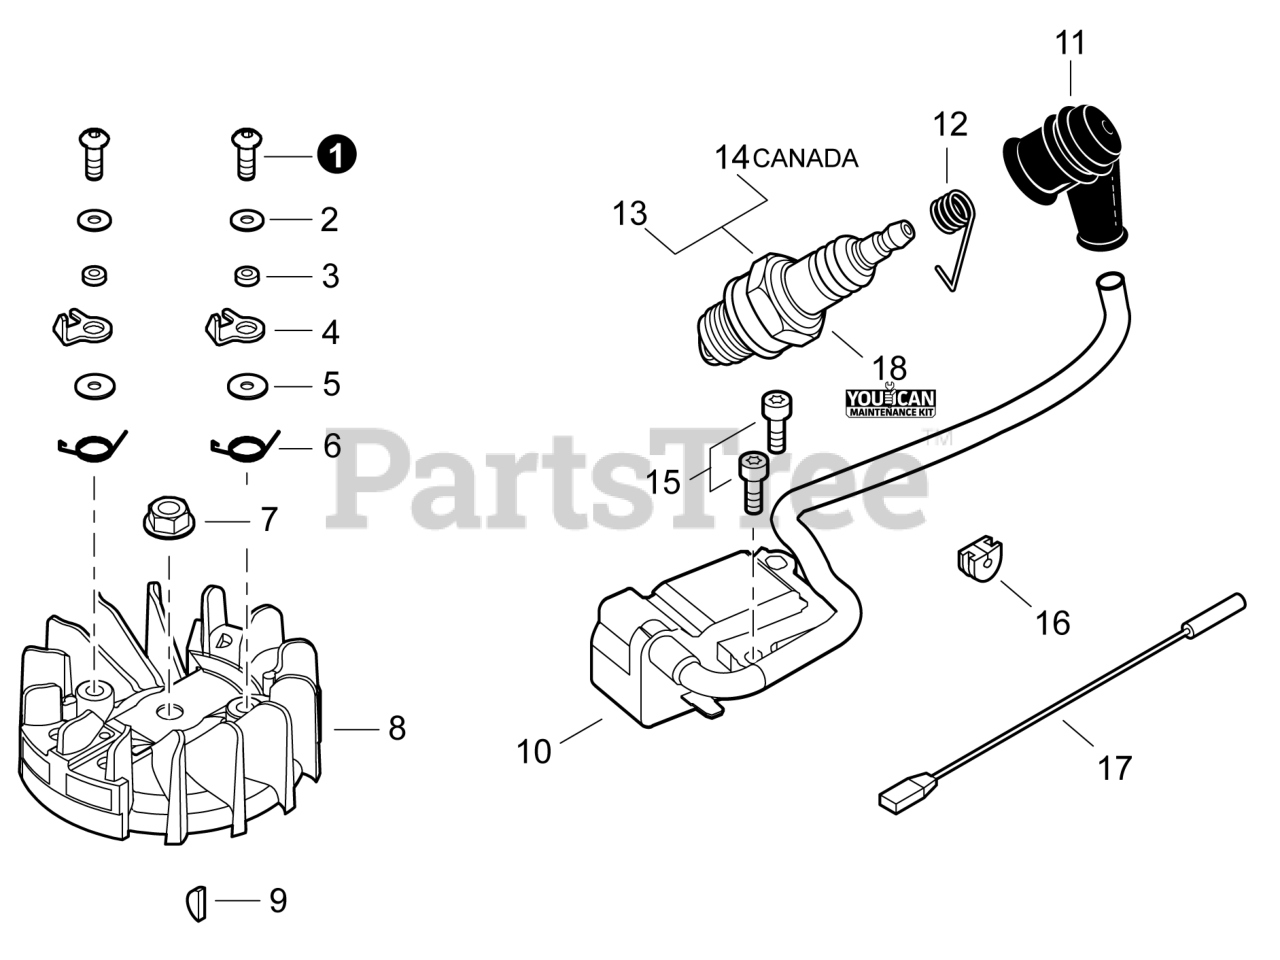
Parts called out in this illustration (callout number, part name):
1	BOLT 5x14
2	WASHER 5.5x12x0.8
5	WASHER 5.5x16x0.8
6	SPRING, TORSION
7	NUT, FLANGE M6
8	FLYWHEEL
9	KEY, WOODRUFF
10	COIL, IGNITION
11	CAP, SPARK PLUG
12	TERMINAL, SPARK PLUG
13	SPARK PLUG - BPM8Y
14	SPARK PLUG - BPMR8Y
15	BOLT, TORX 4x16
17	LEAD L= 85 MM
18	TUNE-UP KIT - YOUCAN?
